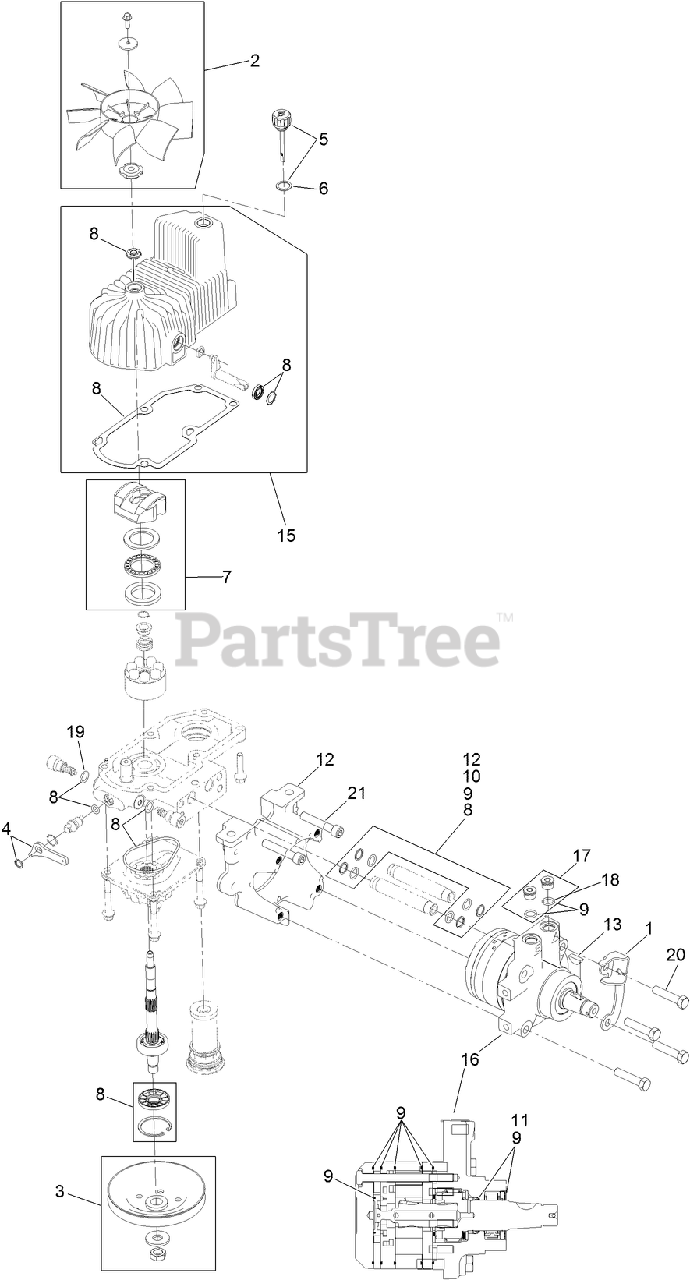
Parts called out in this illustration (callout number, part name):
1	BRACKET-ANCHOR, CABLE
2	FAN KIT
3	PULLEY KIT
4	HANDLE-BYPASS VALVE, HYDRO
5	DIPSTICK-HYDRO W/GASKET
6	GASKET-DIPSTICK, HYDRO
7	SWASH BLOCK KIT
8	PUMP SEAL KIT
9	MOTOR SEAL KIT
10	TUBE SEAL KIT
11	OUTPUT SHAFT SEAL KIT
12	NOSE CUP-UHT
13	KEY-WOODRUFF
15	Housing-RH
16	MOTOR-HYDRAULIC, RH 280CC
17	MAGNETIC PLUGS SERVICE KIT
18	O-RING
19	O-RING-CHECK VALVE
20	SCREW HH
21	SCREW-HSH
